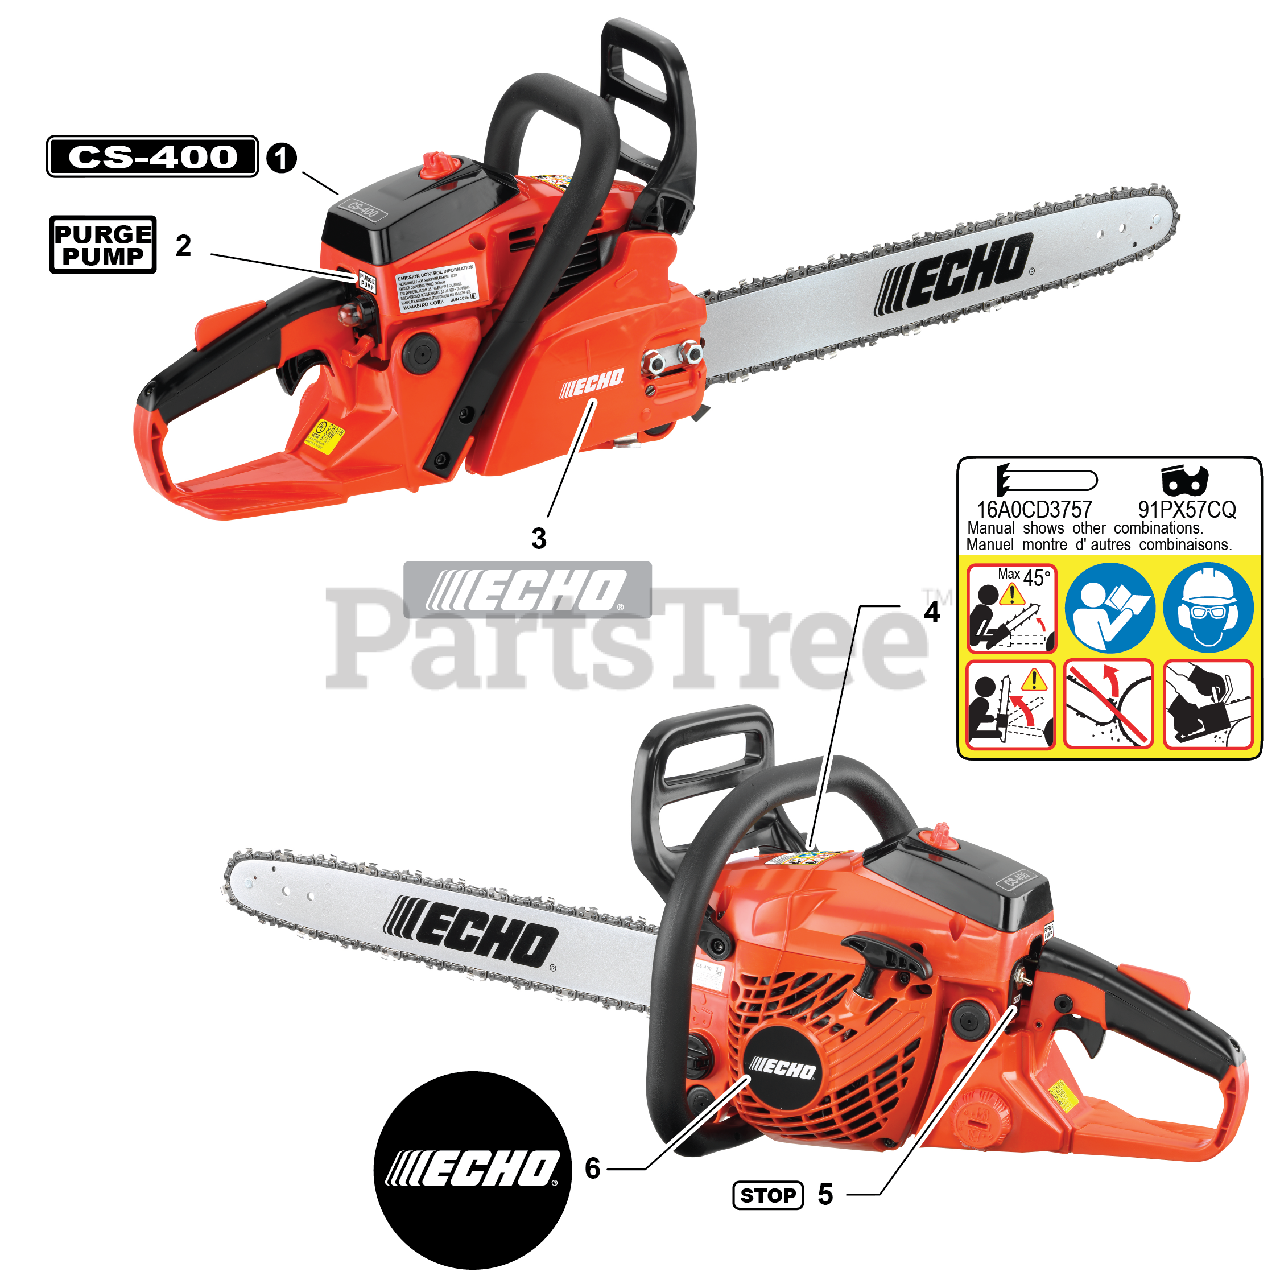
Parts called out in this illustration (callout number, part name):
1	LABEL - MODEL CS-400
2	LABEL - PURGE PUMP
3	LABEL - ECHO
4	LABEL - CAUTION
5	LABEL - STOP
6	LABEL - STARTER - ECHO
